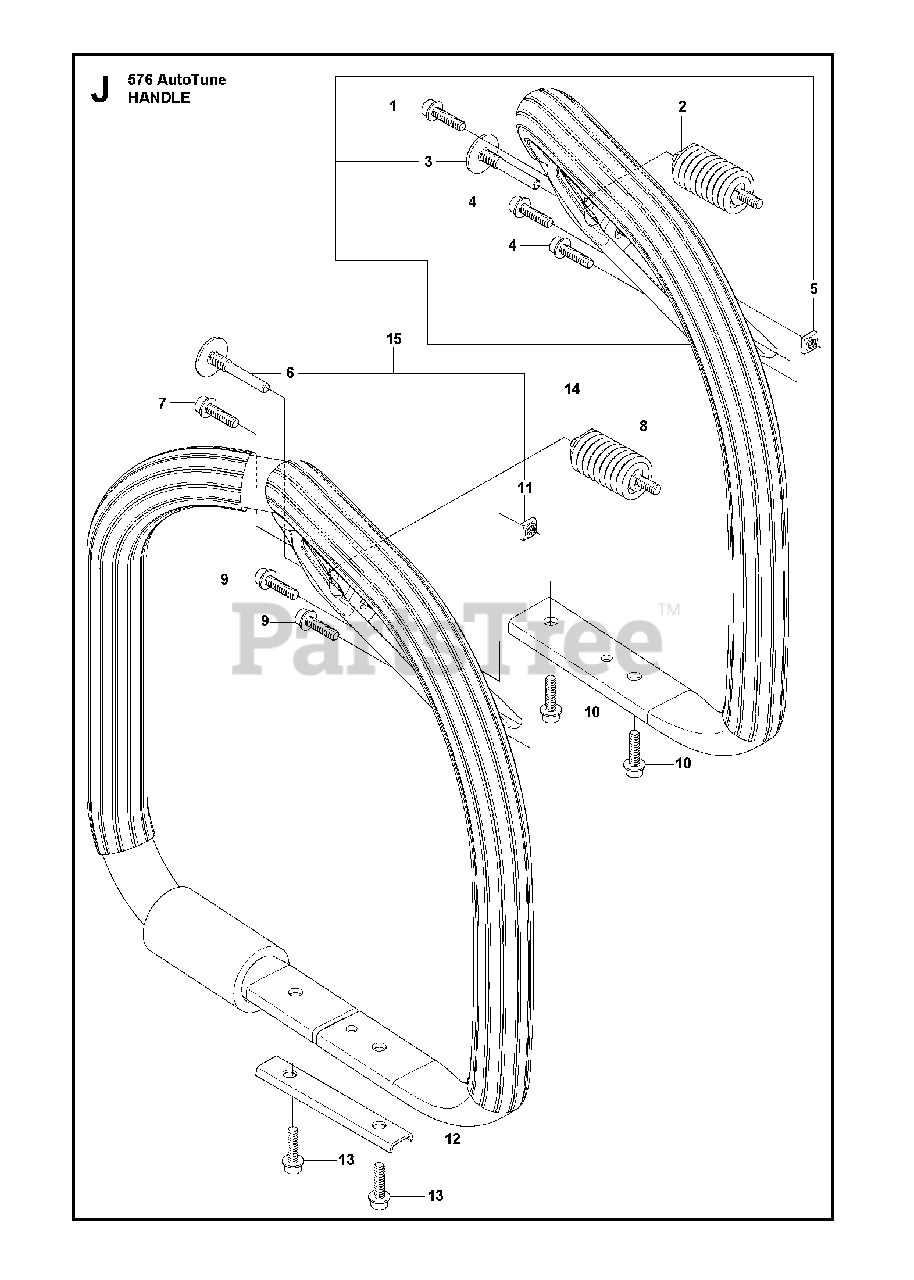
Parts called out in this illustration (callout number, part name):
2	ANTIVIBE MOUNT
3	SCREW
5	NUT
6	SCREW
8	ANTIVIBE MOUNT
11	NUT
14	%FRONT HANDLE
14	FRONT HANDLE ASSY
15	HANDLE
